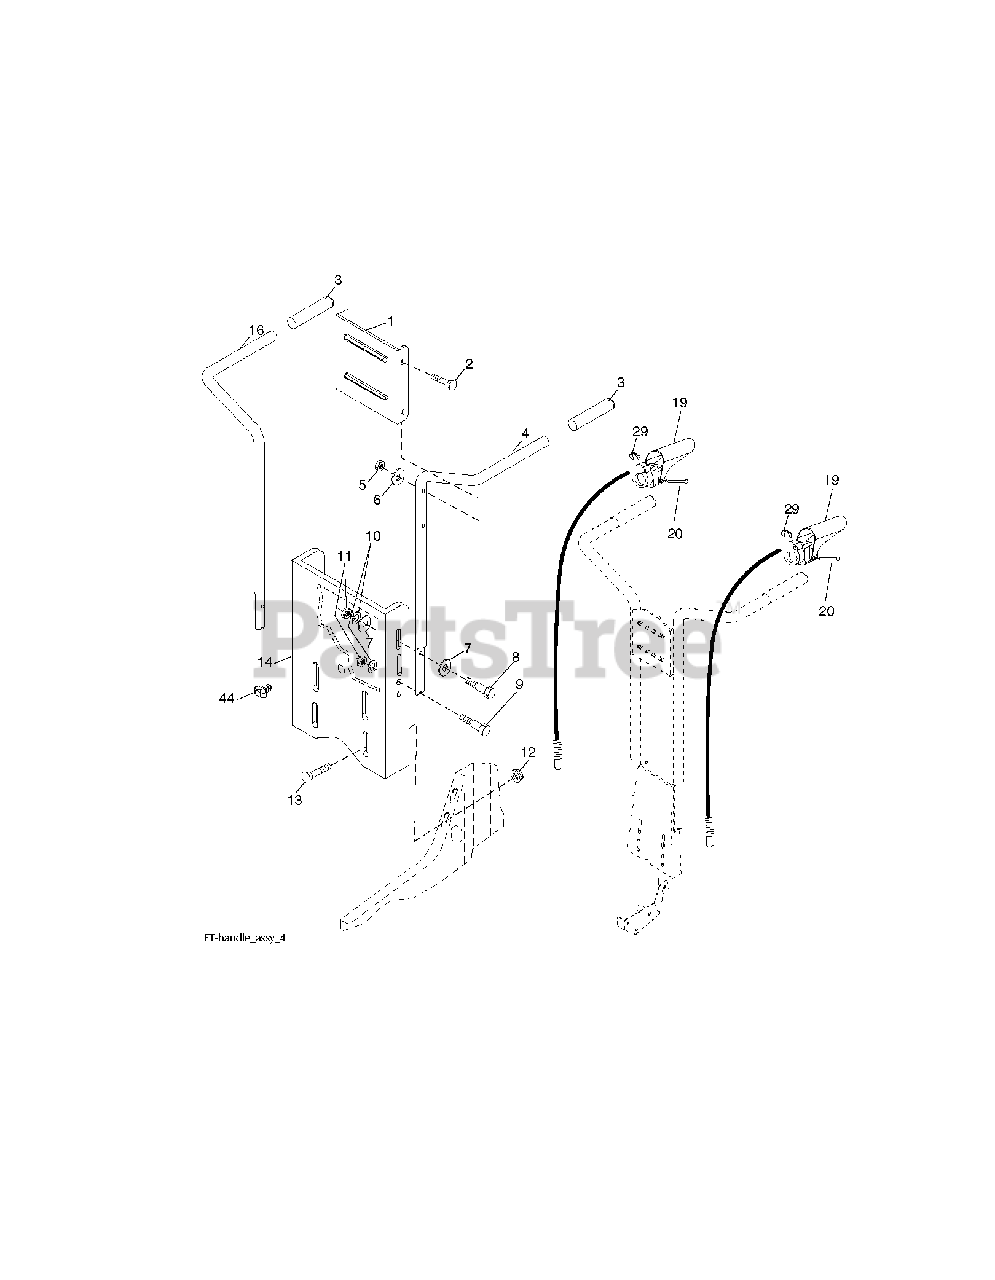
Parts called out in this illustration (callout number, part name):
1	BRACKET.HANDLE.ORANGE
2	BOLT
3	GRIP.HANDLE.BLACK
4	HANDLE.PNT.LH.DOUBLE.BEND
5	LOCKNUT
6	WASHER
7	WASHER
8	BOLT
9	BOLT RB
10	LOCKWASHER
12	NUT
13	BOLT, RDHD SQNK 5/16-18 X 3/4
14	RP PANEL.PNT.HANDLE.ORANGE.
16	HANDLE.PNT.RH.DOUBLE.BEND
19	CONTROL ASM.TINE.49.88
20	PIN, PIVOT
29	RETAINING.RING.#5103-25
